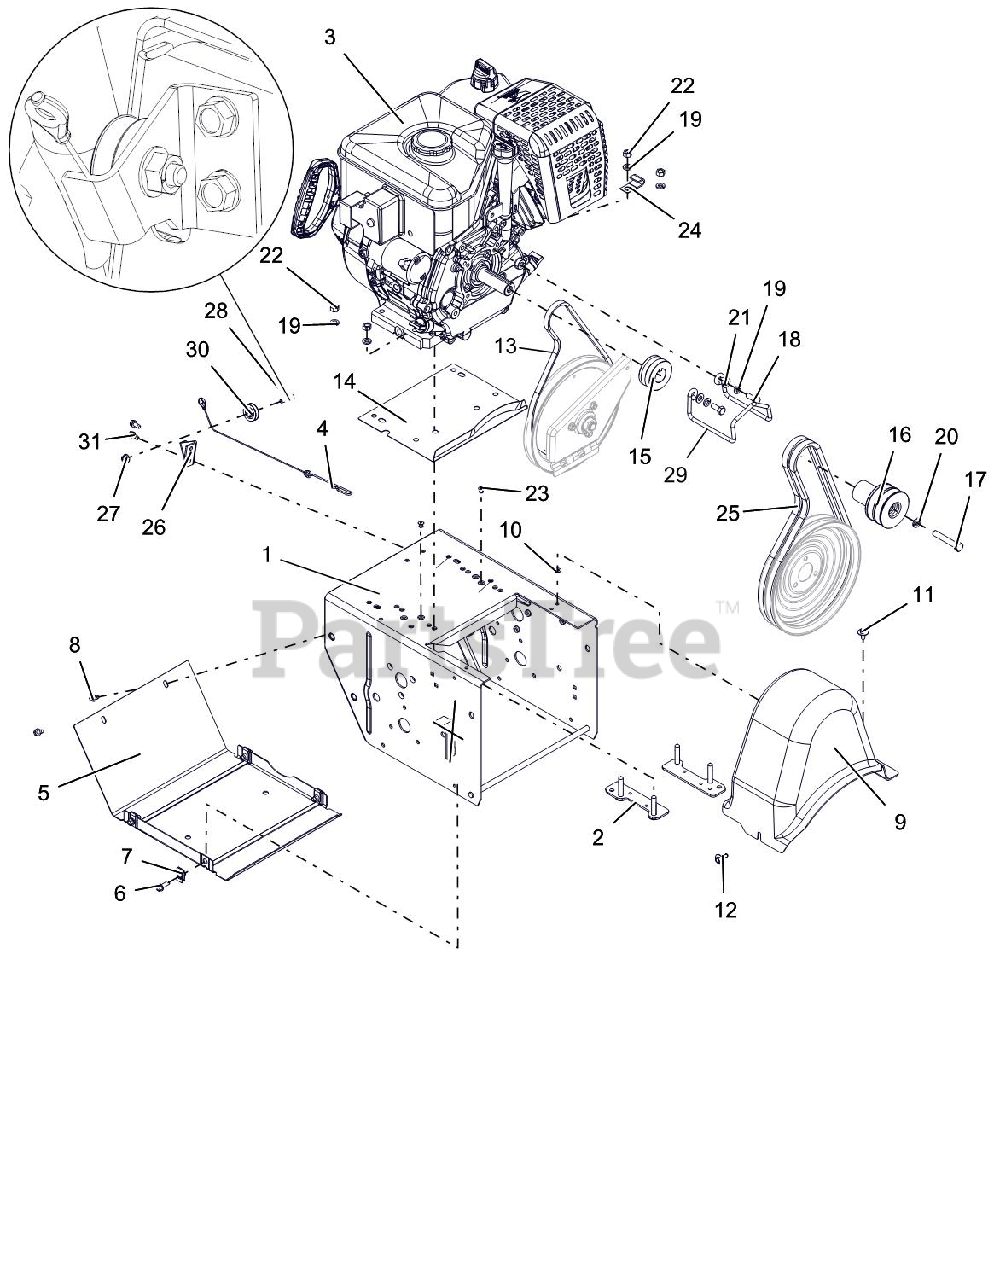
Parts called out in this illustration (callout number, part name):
1	FRAME, MAIN-DELUXE(WELDMENT)
2	STRAP, ENGINE-MEDIUM BLOCK
3	ENGINE, AX306 GEN 3 120V/60W
4	CABLE, LOWER TRACTION,SS & PRO
5	COVER, BOTTOM
6	BLT-HEX .25-20X.75 HWH YZ GR5
7	NUT-RTNR .25-20X.56
8	SCR-TAP .25-20X.50 HWH TR YWZ
9	COVER, BELT-LARGE
10	NUT-PUSH .25X.50 O.D.
11	SCR-TAP .25-20X.50 LGHWH TR YZ
12	SCR-TAP .25-20X.5 CAPTIVE
13	V-BELT, 3L-WRAPPED
14	BAFFLE, WATER - LARGE BLOCK
15	SHEAVE, DRIVE
16	SHEAVE, ATTACHMENT 2-GRV
17	BLT-HEX .38-24X2.25 YWZC GR5
18	BLT-HEX .31-24X.75 YWZC GR5
19	WSHR-LK .312X.097 HVY YWZC
20	@WSHR-LK .38X.094 REG YWZC
21	@WSHR-FL-STL.344X.688X.065YWZC
22	@NUT-HEX .31-18 YWZC
23	RVT-POP .187 YZ
24	J-CLAMP
25	V-BELT, HA-RAW EDGE (SET)
26	BRACKET, CABLE PULLEY
27	@NUT-LK-TOP-FLG .25-20 YWZC
28	BOLT, SHLDR-.375X.375X.25-20
29	FINGER, BELT
30	PULLEY, CABLE
31	SCR-TAP .25-20X.50 HWH TR YWZ
